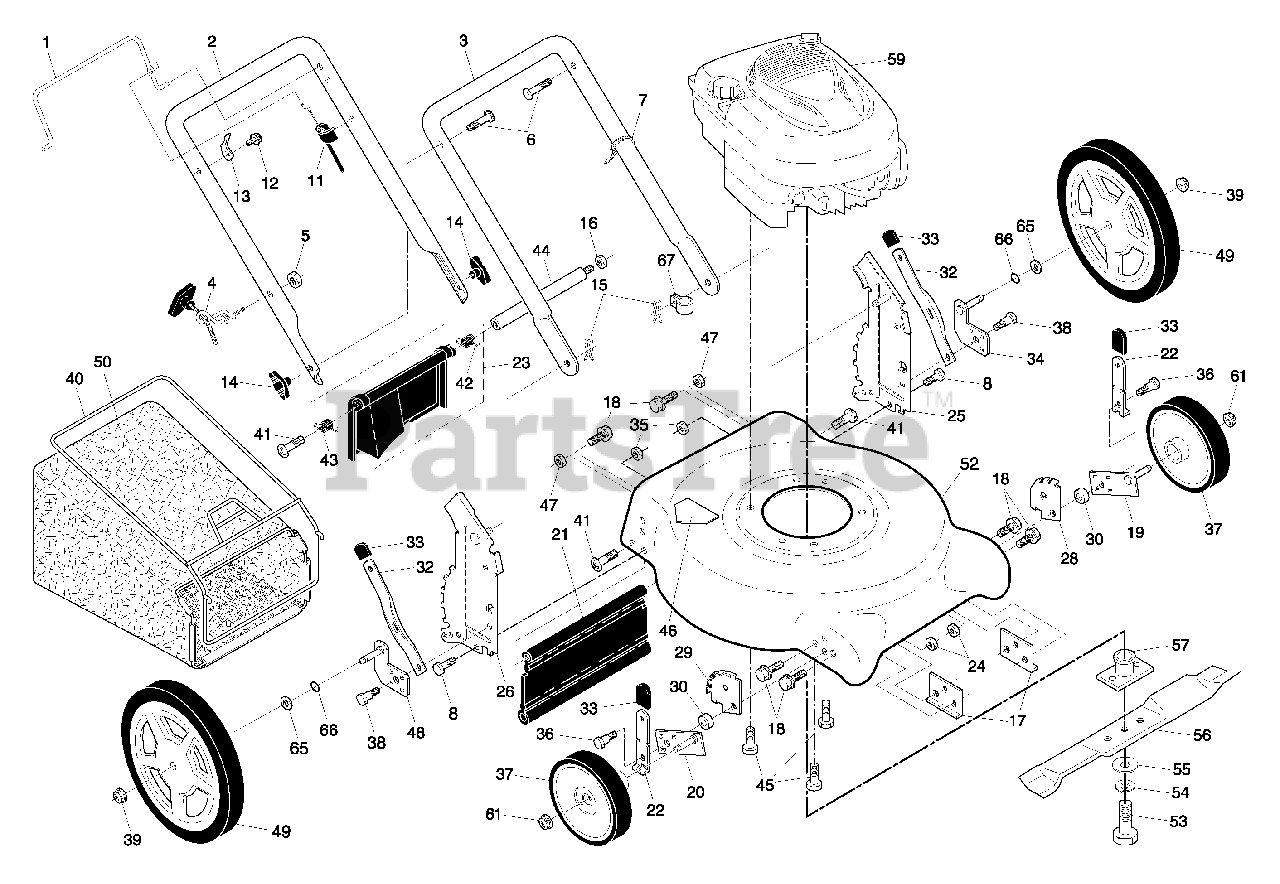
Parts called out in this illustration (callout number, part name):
1	Control Bar
2	Upper Handle
3	Lower Handle
4	Rope Guide
6	Handle Bolt
7	Wire Tie
8	Bolt, Hex Head 5/16-18 x 3/4
11	Engine Zone Control Cable
12	Hex Washer Head Screw #10-24 x 1/2
13	Up-Stop Bracket
14	Handle Knob
15	Hairpin Cotter
16	Nut, Hex, Flangelock
17	Support Bracket
18	Screw
19	Axle Arm Assembly, Front, LH
20	Axle Arm Assembly, Front, RH
21	Rear Skirt
22	Selector Spring, Front
23	Kit, Rear Door Assembly
24	Locknut, Hex 5/16-18
25	Handle Bracket Assembly, LH
26	Handle Bracket Assembly, RH
28	Wheel Adjusting Bracket, Front, LH
29	Wheel Adjusting Bracket, Front, RH
30	Washer
32	Selector Spring, Rear
33	Selector Knob
34	Axle Arm Assembly, Rear, LH
35	Locknut, Hex 5/16-18
36	Shoulder Bolt 5/16-18
37	Wheel & Tire Assembly, Front 7 x 1-3/4
38	Bolt, Shoulder
39	Nut, Hex
40	Frame, Grassbag
41	Hinge Screw
42	Spring, LH
43	Spring, RH
44	Door Bolt
45	Hex Head Thread Rolling Screw 3/8-16 x 1
46	Danger Decal
47	Nut, Hex
48	Axle Arm Assembly, Rear, RH
49	Wheel & Tire Assembly, Rear 12 x 1-3/4
50	Grassbag
52	Housing Assembly
53	Hex Head Screw 3/8-24 x 1-3/8 Grade 8
54	Helical Lockwasher
55	Hardened Washer
56	21" Blade
57	Blade Adapter
61	Flanged Locknut
65	Washer, Flat
66	O-Ring
67	Clip, Cable
